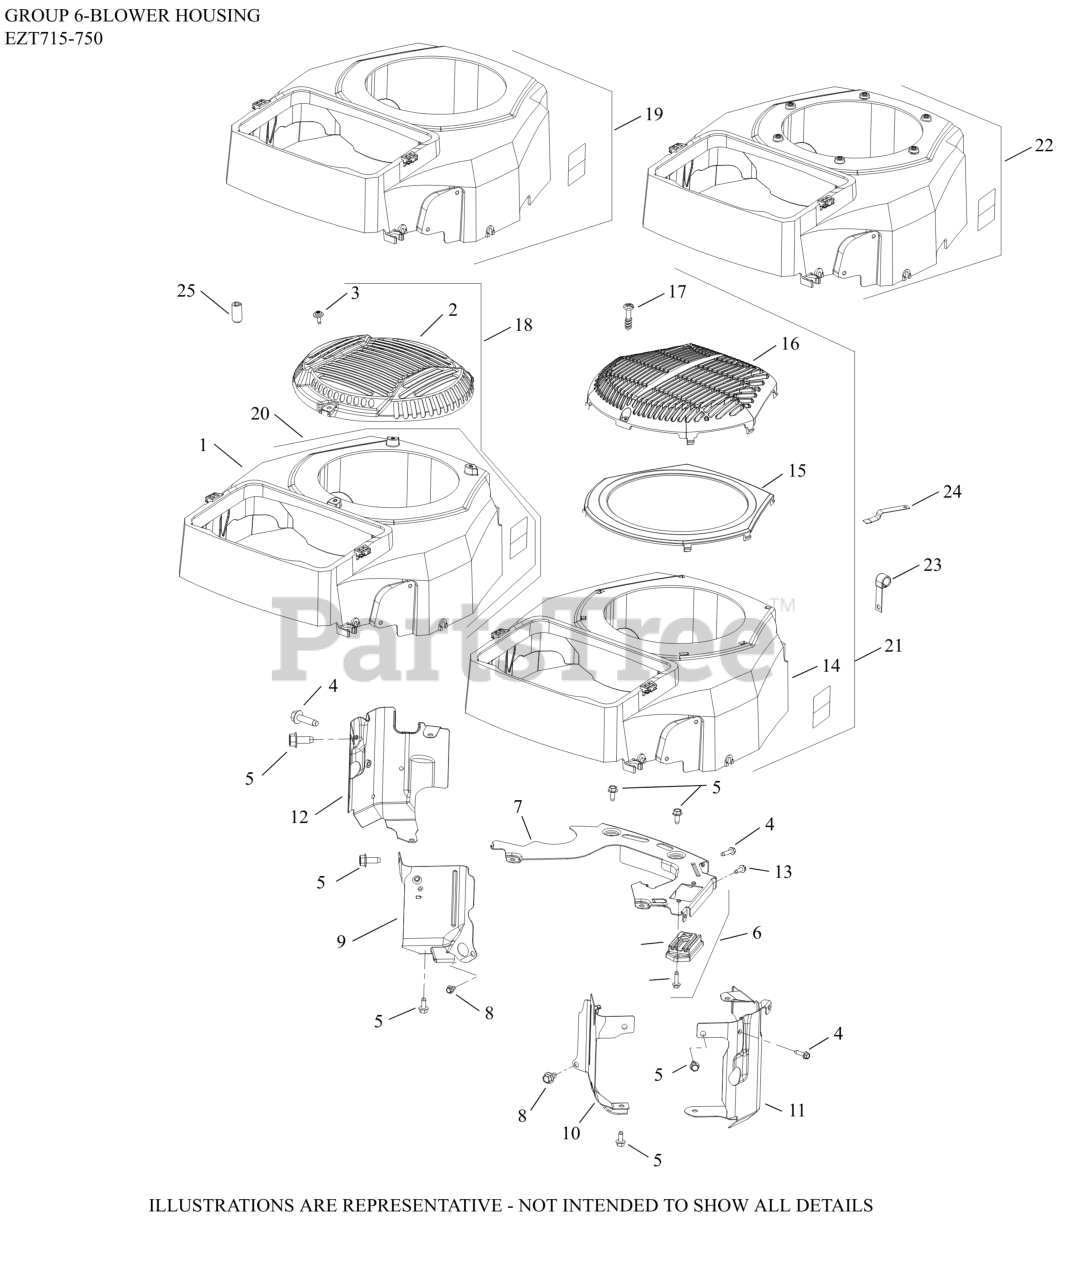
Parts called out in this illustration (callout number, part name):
1	KIT, BLOWER HOUSING
2	GUARD, GRASS SCREEN (METAL)
3	SCREW, SEMS
4	SCREW, THD FRM-USE 25 086 473-S
5	SCREW, THREAD FORMING
6	PLATE ASSEMBLY, BACKING (15A)
7	PLATE, BACKING
8	SCREW, THREAD FORMING
9	BAFFLE, VALLEY #1
10	BAFFLE, VALLEY #2
11	BAFFLE, LEFT BARREL
12	BAFFLE, RIGHT BARREL
13	SCREW, THREAD FORMING
